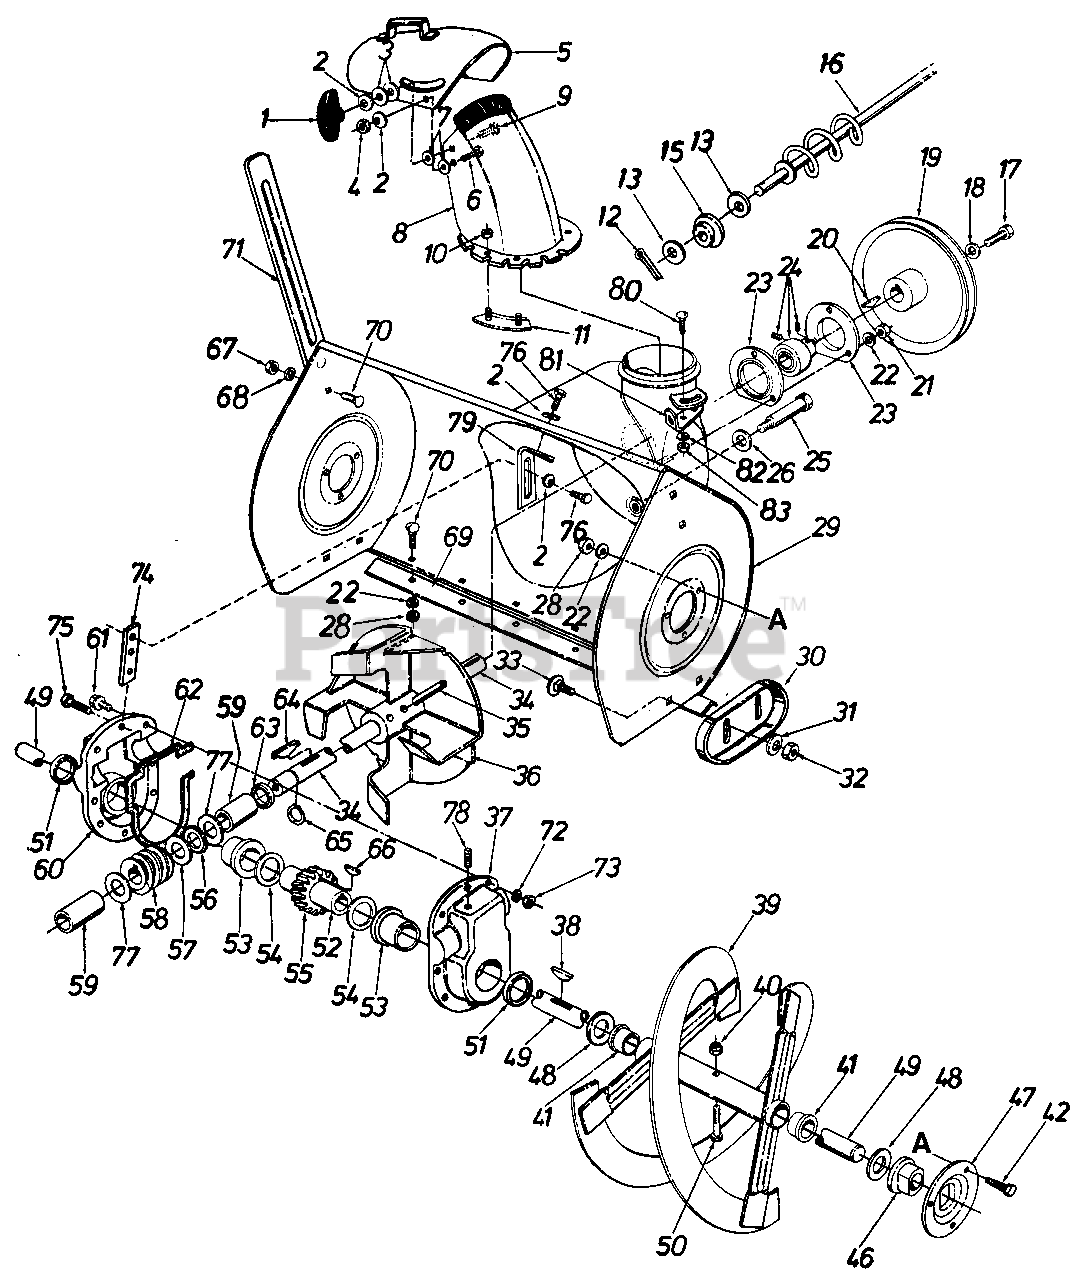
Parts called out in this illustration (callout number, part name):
1	Hand Knob Ass'y.
2	Bell-Wash. .345 I.D. x .88 O.D. x .060
3	Fl. Wash. .312 I.D. x 1.125 O.D. x .125
4	Hex Cent. L-Nut 5/16-18 Thd.
5	Top Chute Ass'y.
6	Carr. Bolt 5/16-18 x .62" Lg.
7	Fl-Wash. .53 I.D. x 1.25 O.D. x .100
8	Chute Ass'y.
9	Carr. Bolt 5/16-18 x 1.00" Lg.
10	Hex Cent. L-Nut 1/2-20 Thd.
11	Chute Flange Keeper Ass'y.
12	Cotter Pin
13	Fl-Wash. .385" I.D. x .62" O.D.
15	Bushing
16	Chute Crank Ass'y.
17	Hex L-Scr. 5/16-18 x .88" Lg.
18	Bell-Wash. .345 I.D. x .88 O.D. x .060
19	V-Pulley .875 I.D. x 10.12 O.D.
20	#9 Hi-Pro Key 3/16 x 3/4" Dia.
21	Hex Nut 5/16-18 Thd.*
22	L-Wash. 5/16" Scr.*
23	Bearing Hsg.-Self Aligning Brg.
24	Self Aligning Brg. .875 I.D.
25	Stud 3/8-16 x 2.75" Lg.
26	Bell-Wash. .400 I.D. x .88 O.D. x .060
28	Hex Nut 5/16-18 Thd.*
29	Blower Hsg. Ass'y.
30	Slide Shoe
31	Bell-Wash. .400 I.D. x .88 O.D. x .060
32	Hex Jam Nut 3/8-16 Thd.
33	Carr. Bolt 3/8-16 x .62" Lg.
34	Blower Axle
35	Spring Pin Spiral 5/16" Dia. x 1.75" Lg.
38	#91 Woodruff Key 1/4" X 3/4" Dia.
41	Plastic Bushing
42	Hex Sems Scr. 5/16-18 x .75" Lg.*
46	Flange Brg. w/ Flats 1.0" I.D.
47	Bearing Hsg.-Spiral Hsg.
48	Fl-Wash. 1.06 I.D. x 1.75" O.D. x .100
49	Spiral Axle-26"
50	Hex Bolt 5/16-18 x 1.75" Lg.
51	Oil Seal 1.50" I.D.
52	Worm Gear Shaft
53	Flange Brg. 1.503 I.D.
54	Fl-Wash. 1.50 I.D. x 2.00 O.D. x .030
55	Double Threaded Worm Gear
56	Thrust Brg. .88 I.D. x 1.44 O.D. x .078
57	Fl-Wash. .88 I.D. x 1.40 O.D. x . 1 50
58	Double Threaded Worm-L.H.
59	Sleeve Brg. .875 I.D.
60	Complete Gear Hsg. Half-R.H.
61	Hex Scr. 5/16-18 x 1.00" Lg.
62	Gasket
63	Oil Seal .875" I.D.
64	#9 Hi-Pro Key 3/16 x 3/4" Dia.
65	Snap Ring for .875" Dia. Shaft
66	#91 Woodruff Key 1/4 X 3/4" Dia.
67	Hex Nut 5/16-18 Thd.*
68	L-Wash. 5/16" Scr.*
69	Shave Plate-26"
70	Carr. Bolt 5/16-18 x .62" Lg.
71	Drift Cutter
72	Wave Wash. 5/16" Scr.*
73	Hex Ins. L-Nut 5/16-18 Thd.
74	Gear Hsg. Support Plate
75	Hex Scr. 5/16-18 x 1.25" Lg.
76	Hex Wash. Hd. Self-Tap Scr. 5/16-18 x .75" Lg.
77	Fl-Wash. .88 I.D. x 1.40 O.D. x .1 50
78	Filler Plug
79	Gear Hsg. Support Brkt.
80	Carr. Bolt 5/16-18 x .75" Lg.*
81	Chute Crank Bracket
82	Bell-Wash. .345 I.D. x .88" O.D.
83	Hex Nut 5/16-18 Thd.*
